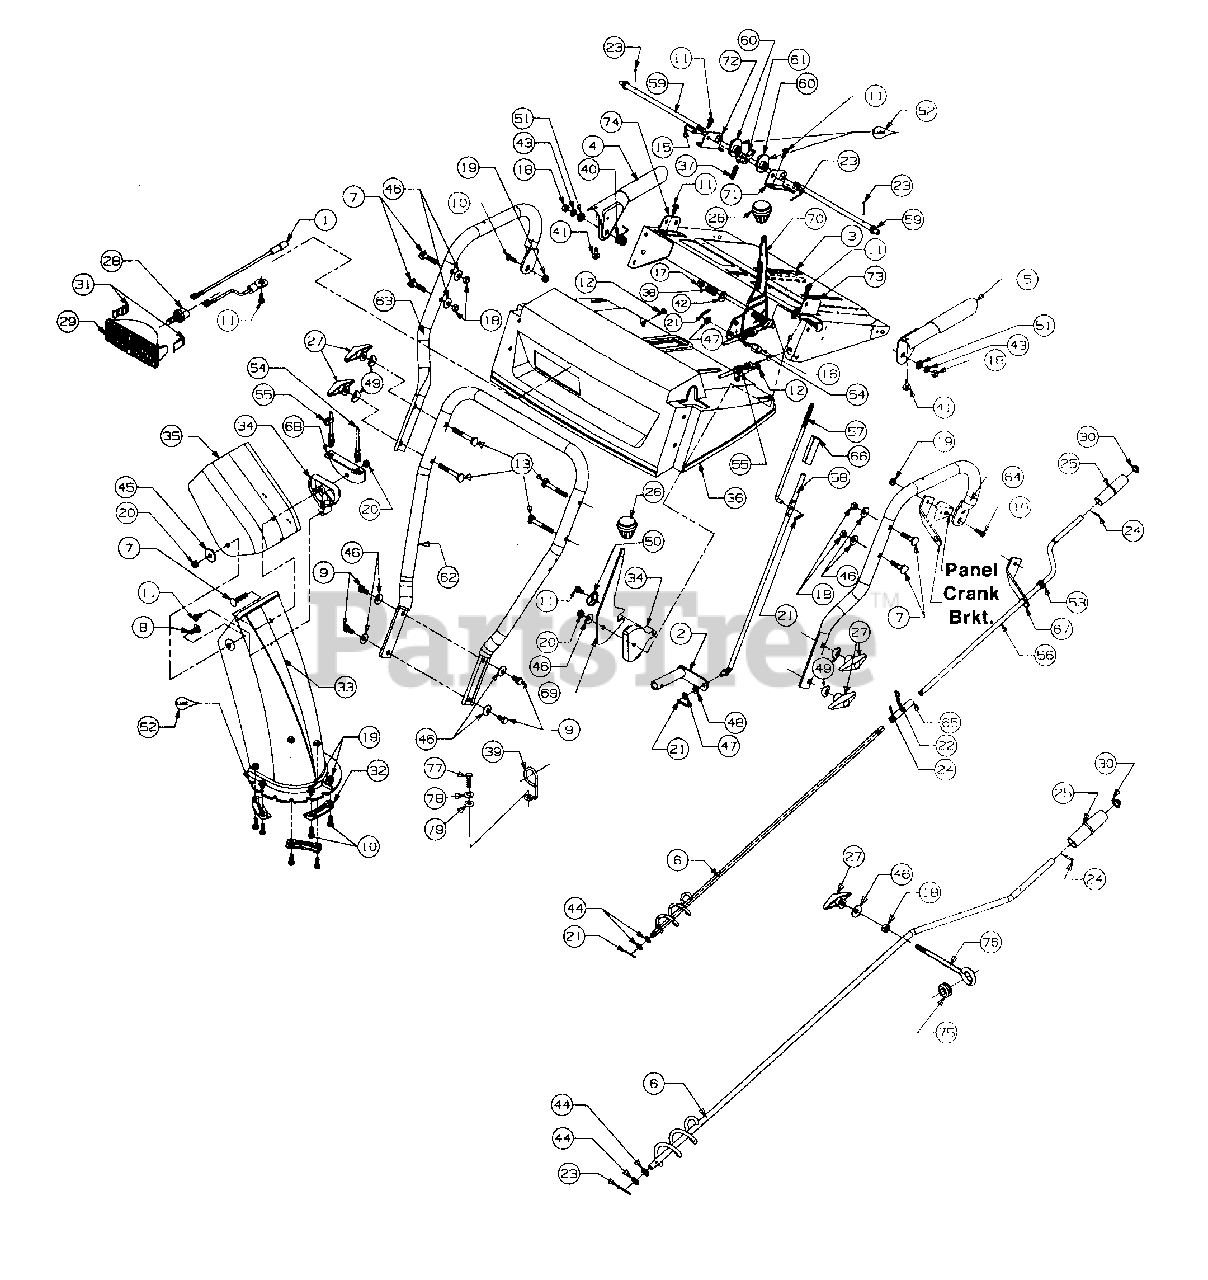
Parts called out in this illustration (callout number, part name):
1	Harness-Light
4	Handle-Engagement - R.H.
5	Handle-Engagement - L.H.
6	Crank-Chute (522E, 724E)
8	Bolt-Carriage
9	Screw-Hex
10	Screw-Hex
11	Screw-Washer Head-Hex
12	Screw-Hex
13	Bolt-Carriage
15	Pin-Clevis
16	Ferrule
17	Nut-Hex Lock
19	Nut-Hex Lock
20	Nut-Hex Lock
21	Pin-Cotter Internal
22	Pin-Cotter
23	Pin-Cotter
24	Pin-Roll
25	Knob-Chute Crank
26	Knob-Shift
27	Knob-Wing Nut
28	Lamp
29	Housing-Lamp
31	Clip-Retaining
32	Keeper-Chute
33	Chute-Lower
34	Guide-Cable
35	Chute-Upper
36	Panel-Handle
39	Wire-Control
42	Washer-Bell
43	Washer-Lock
44	Washer-Flat
46	Washer-Bell
47	Washer-Flat
48	Washer-Lock
49	Washer-Saddle
50	Washer
52	Lubricant
53	Bushing-Plastic
54	Cable-Chute Control
55	Cable-Chute Control
56	Crank-Chute
57	Rod-Shift Upper
58	Rod-Shift Lower
60	Cam-Handle Lock
61	Pawl-Handle Lock
63	Handle - R.H.
66	Connector
70	Handle-Shift
75	Grommet Rubber (522E, 724E)
76	Eyebolt-Chute (522E, 724E)
77	Screw-Washer Head-Hex (522E, 724E)
78	Washer Lock(522E,724E)
79	Washer-Flat (522E, 724E)
